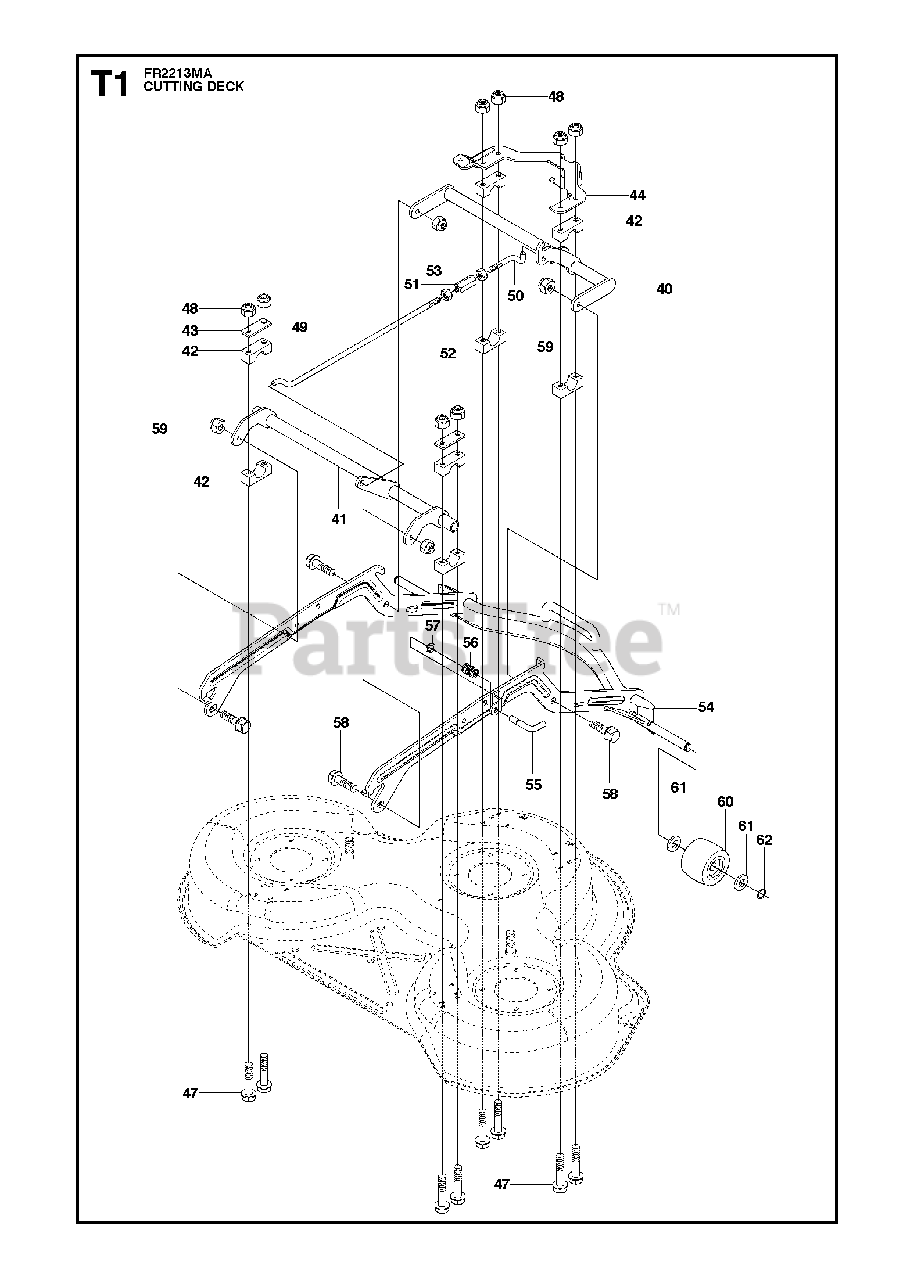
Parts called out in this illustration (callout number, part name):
48	LOCKNUT M8
59	LOCKNUT M8
60	DECK ROLLER, FRONT
62	RETAINING RING SGA 15
